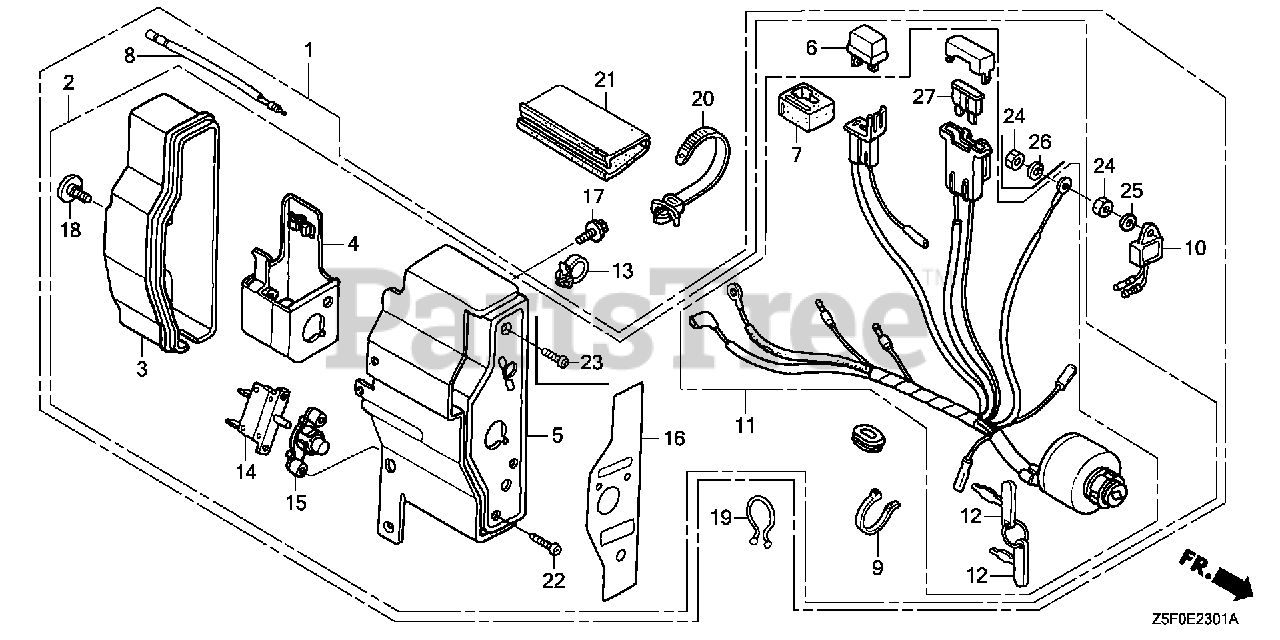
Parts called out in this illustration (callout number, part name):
1	BOX ASSY., CONTROL (3A) *NH1* (EXP-ALERT) (BLACK)
1	BOX ASSY., CONTROL (3A) *R280* (EXP-ALERT) (POWER RED)
3	CASE, CONTROL
4	BRACKET, CASE MOUNTING
5	PANEL, CONTROL *NH1* (BLACK)
5	PANEL, CONTROL *R280* (POWER RED)
6	RECTIFIER ASSY., SILICON (SHINDENGEN)
7	SUSPENSION, CONNECTOR
8	SUB-WIRE HARNESS
9	BAND
10	ALERT UNIT, OIL
11	SWITCH ASSY., COMBINATION (3A-CHARGE)
12	KEY
13	HOLDER, STOP SWITCH WIRE Use up to Engine SN 2056819.
14	PROTECTOR, CIRCUIT (3.5A)
15	LENS ASSY., PROTECTOR
16	MARK, CONTROL BOX (EXTERNAL)
17	BOLT, FLANGE (6X12) (CT200)
18	SCREW, SPECIAL (6X12)
19	CLIP, PURSE LOCK
20	STRAP, CABLE (118MM) *NH1L* (Honda Code 1170653). (BLACK)
21	TUBE, FASTENER (30)
22	SCREW, PAN (3X12)
23	SCREW, PAN (4X12)
24	NUT, HEX. (4MM)
25	WASHER, PLAIN (4MM)
26	WASHER, SPRING (4MM)
27	FUSE, BLADE (15A)
